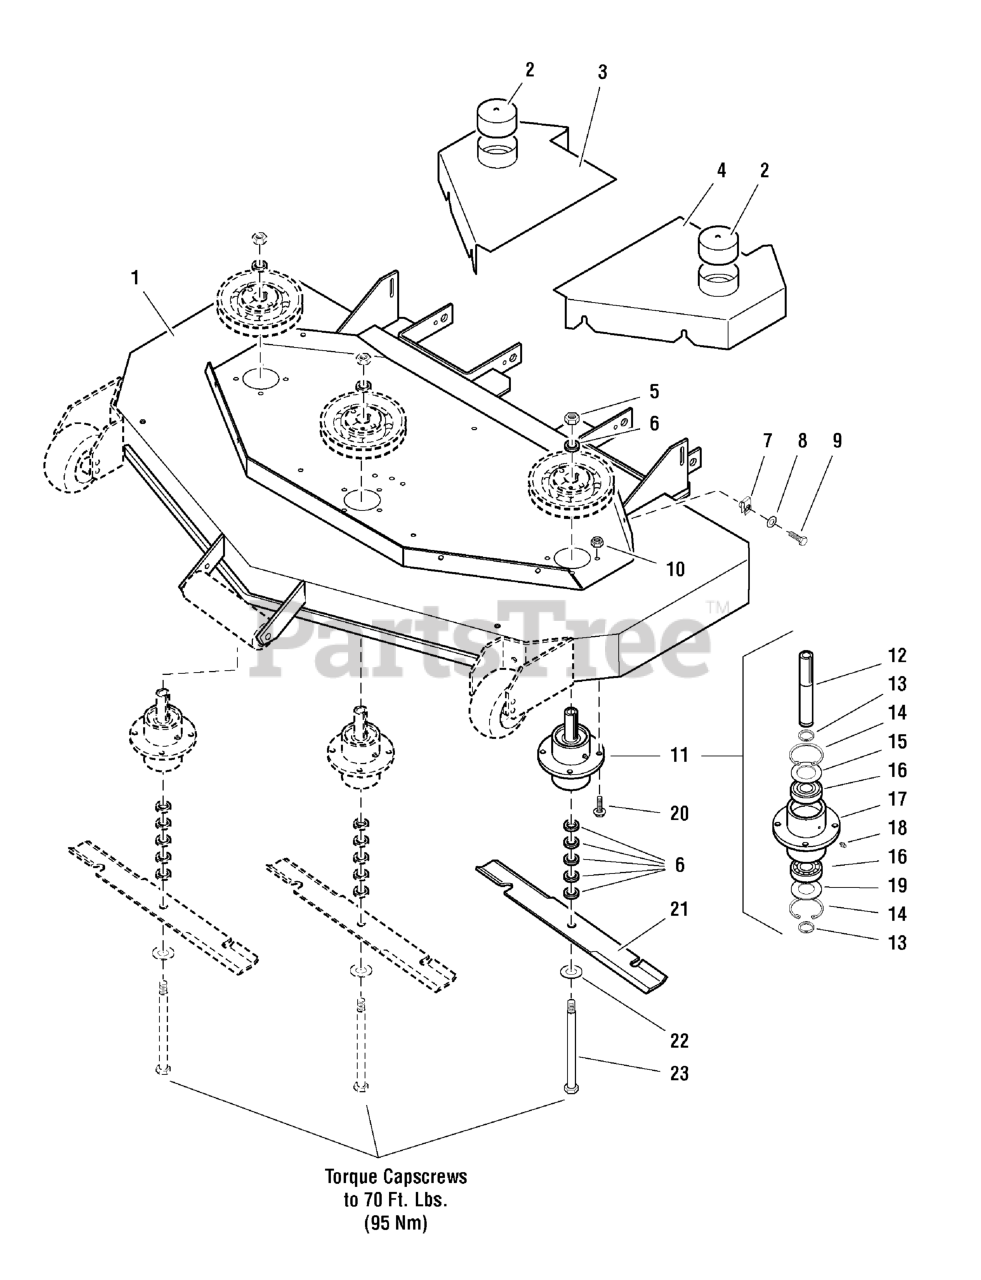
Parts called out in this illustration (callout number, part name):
1	61" RD MOWER HOUSING ASSEMBLY
2	VINYL CAP
3	DECK SHIELD - RH
4	DECK SHIELD - LH
5	NUT, 5/8-11 Hex
6	SPACER, .63 x 1.06 x .23
7	BODY CLIP, 5/16-18-7GA MATERIAL
8	WASHER, 5/16" SAE
9	BOLT, 5/16-18 X 3/4 GD5
10	NUT, 5/16-18 Hex Nylon Lock
11	SPINDLE ASSEMBLY, Complete
12	SPINDLE SHAFT
13	SNAP RING, External
14	SNAP RING, Internal
15	SPINDLE WASHER, Top
16	BEARING
17	SPINDLE HOUSING
18	GREASE FITTING
19	SPINDLE WASHER, Bottom
20	BOLT, Flange Head, 5/16-18 x 1-1/4
21	MOWER BLADE, SAND, 21"
22	WASHER, 5/8" GRADE 8, YZ
23	BOLT, 5/8-11 x 9-1/2
